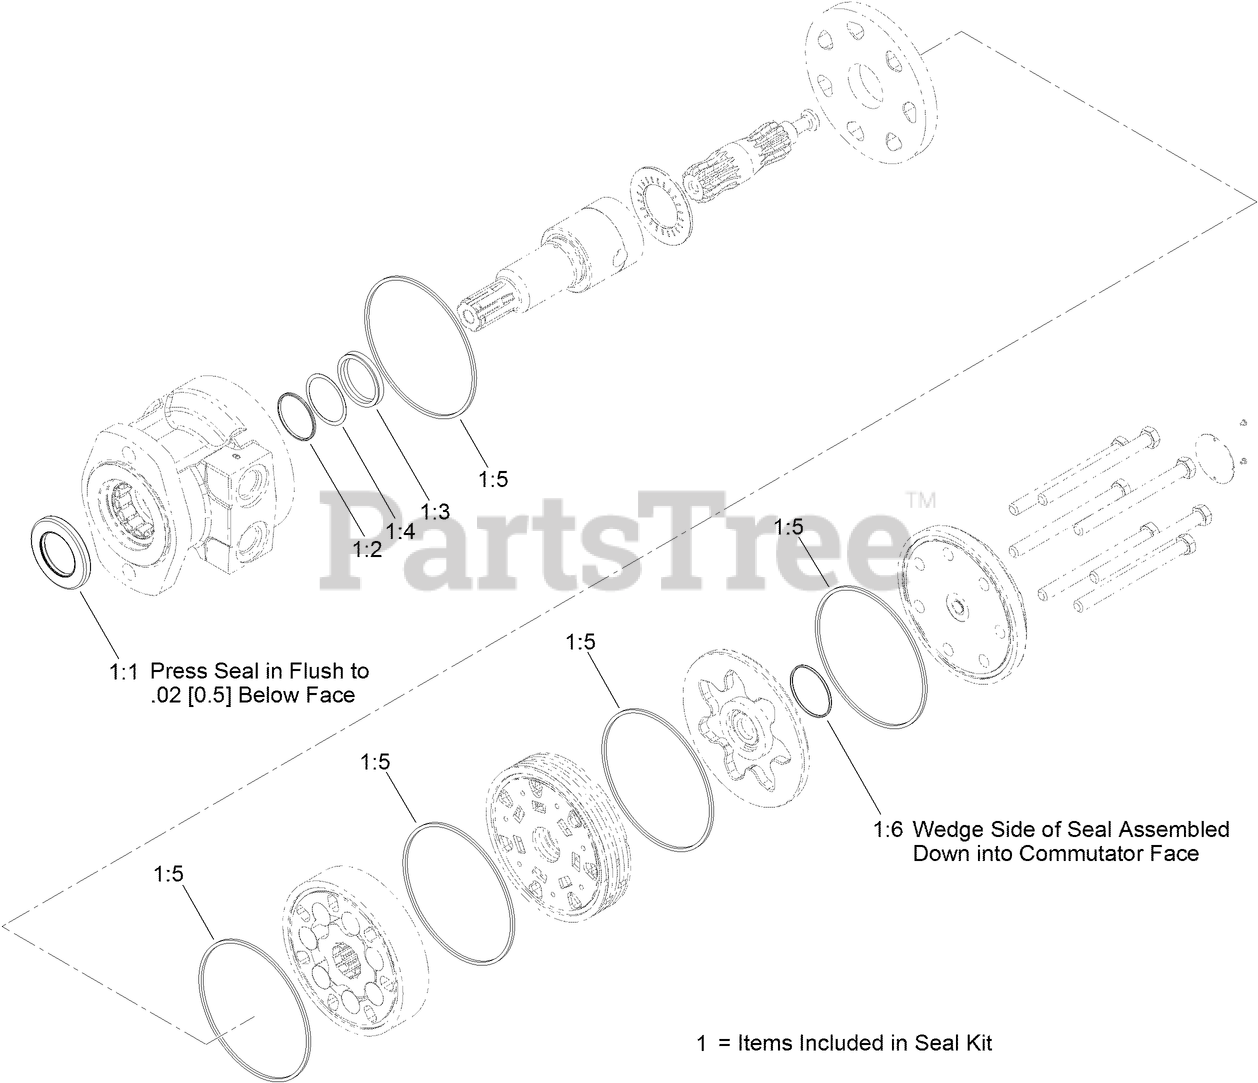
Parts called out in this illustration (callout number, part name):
1	SEAL KIT
1:1	Seal-Dirt and Water
1:2	BACKUP-RING
1:3	SEAL-Shaft
1:4	Washer-Back Up
1:5	SEAL-SQUARE, RING (INNER)
1:6	Seal-Commutator
